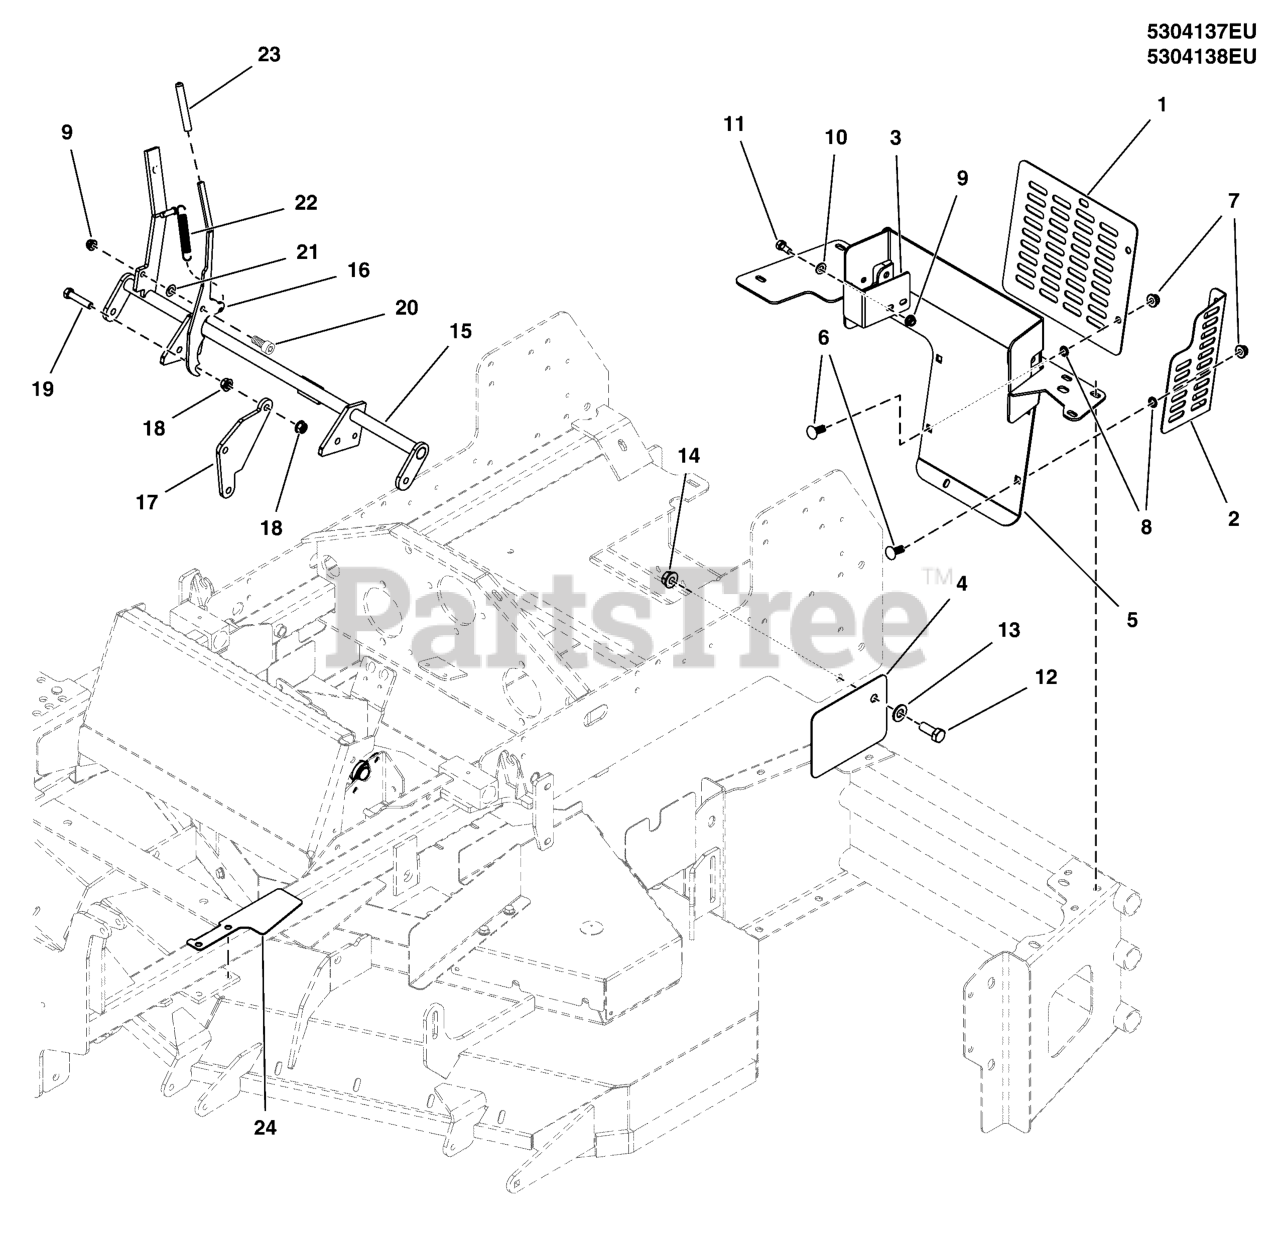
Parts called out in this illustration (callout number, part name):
1	PLATE, PULLEY GUARD, REAR PTO - RED
2	PLATE, PULLEY GUARD, REAR PTO - LH - RED
3	PLATE, PULLEY GUARD, REAR PTO - RH - RED
4	PLATE, BELT GUARD, REAR PTO - RED
5	WELD, GUARD, PTO BELT EU - RED
6	BOLT,3/8-16X1.00,RD SH SQ NK,GR 5,ZC/CL
7	NUT, 3/8-16 HEX NYLOCK FLANGE
8	3/8 PUSHNUT BOLT RETAINER
9	NUT, 5/16-18 HEX NYLOCK FLANGE
10	WASHER, 5/16" SAE
11	BOLT, 5/16-18 X 3/4 GD5
12	BOLT, 1/2-13 X 1-1/4 GD5 CZ
13	WASHER, 1/2 SAE
14	NUT, Hex Flange, Nylock, 1/2-13
15	WELD, HANDLE, BRAKE, 2500, EU - BLK
16	LEVER, BRAKE, 2500, EU - BLK
17	PLATE,SUPPORT,PARKING BRK,IS2500 EU -RED
18	NUT, 3/8-16 HEX SERRATED FLANGE
19	BOLT, 3/8-16 X 1-3/4" GD5 CZ
20	SCREW, TRUSS HD TORX DR5/16-18X0.875 BLK
21	WASHER,WAVE,M10
22	SPRING-EXT, .500 OD X 3.50 LG X .058 WR
23	COVER, VINYL HANDLE
24	PLATE, DECK SHIELD, FRAME - LH - RED
